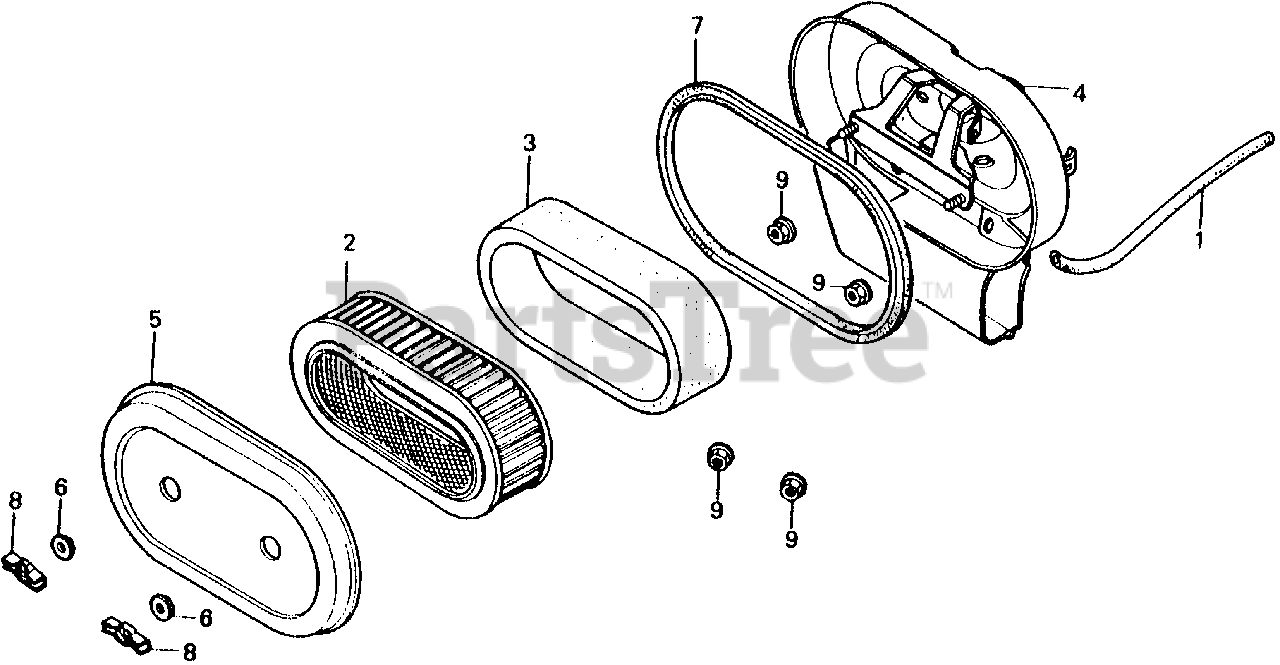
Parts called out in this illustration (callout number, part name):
1	TUBE, BREATHER
2	ELEMENT, CLEANER
3	FILTER (OUTER)
4	HOUSING, AIR CLEANER (NOT AVAILABLE)
5	COVER, AIR CLEANER *NH116M* (URBAN SILVER METALLIC)
6	GROMMET, AIR CLEANER
7	GASKET, AIR CLEANER COVER
8	WINGNUT, AIR CLEANER COVER
9	NUT, FLANGE (6MM)
